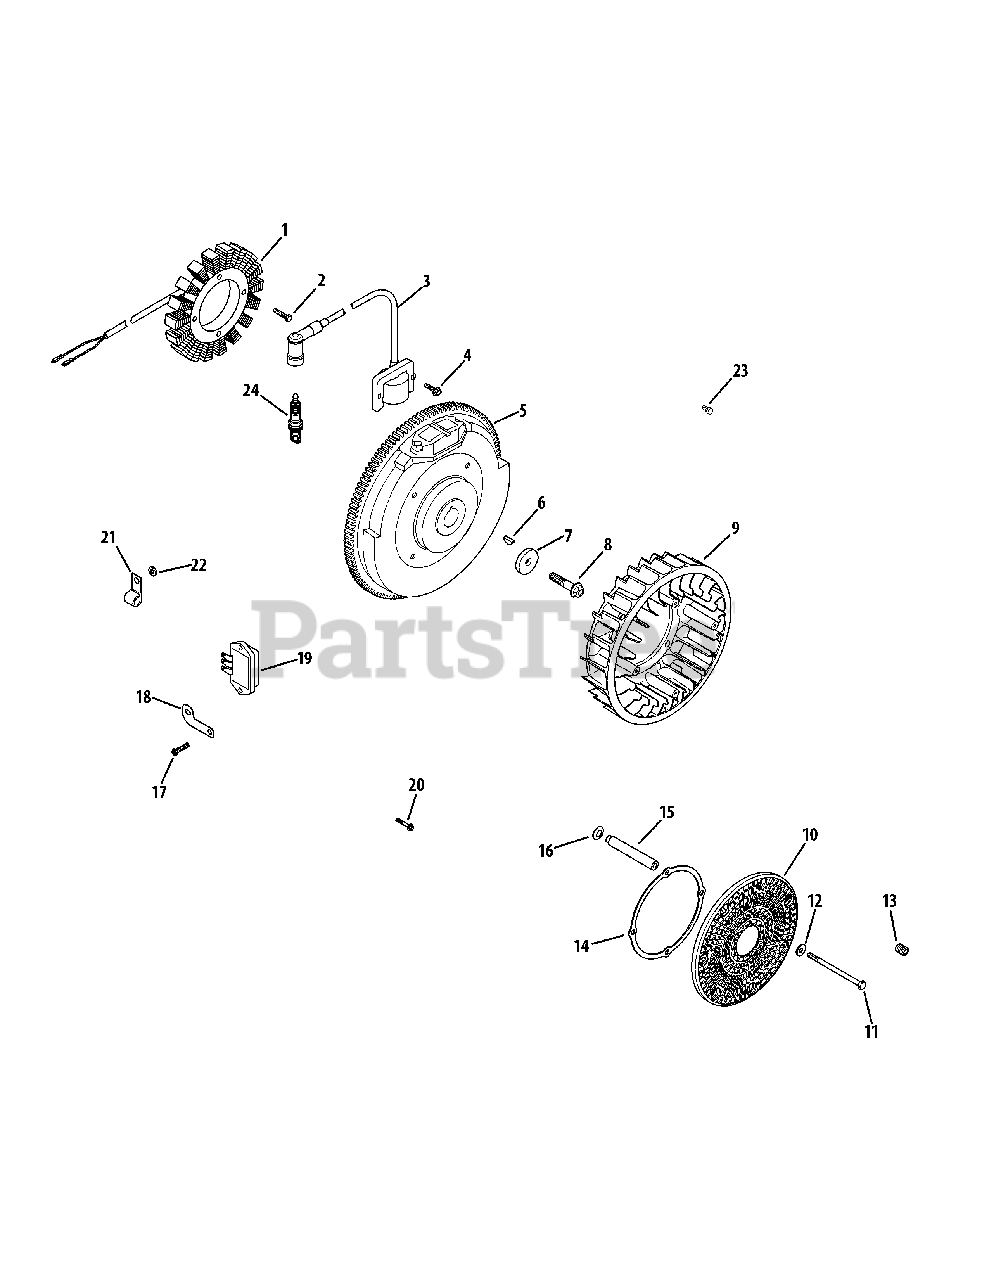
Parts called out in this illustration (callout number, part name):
1	15/20 Amp Stator Kit
2	Thread Forming Screw
3	Module Ignition Key (CDI Fixed)
4	Thread Forming Screw
6	Key, 3/16 x 5/8
7	Flat Washer, 13/32
8	Flange Screw, M10 x 1.5 x 45
9	Fan
11	Cap Screw, M6 x 1.0 x 99.5
12	Flat Washer, 1/4 x 5/8
13	Set Screw, #10-24 X 1/4
14	Support Ring
16	Spring Washer, 10 MM
17	Hex Flange Hi-Lo Screw
18	Ground Strap Bracket
19	Regulator/Rectifier
20	Flange Screw, M8 x 1.25 x 45
21	Cable Clip
22	Flat Washer, 1/4 x 1/2
23	Washer Head Tap Screw, #8-18 x 1/2
24	Spark Plug (Std.)
